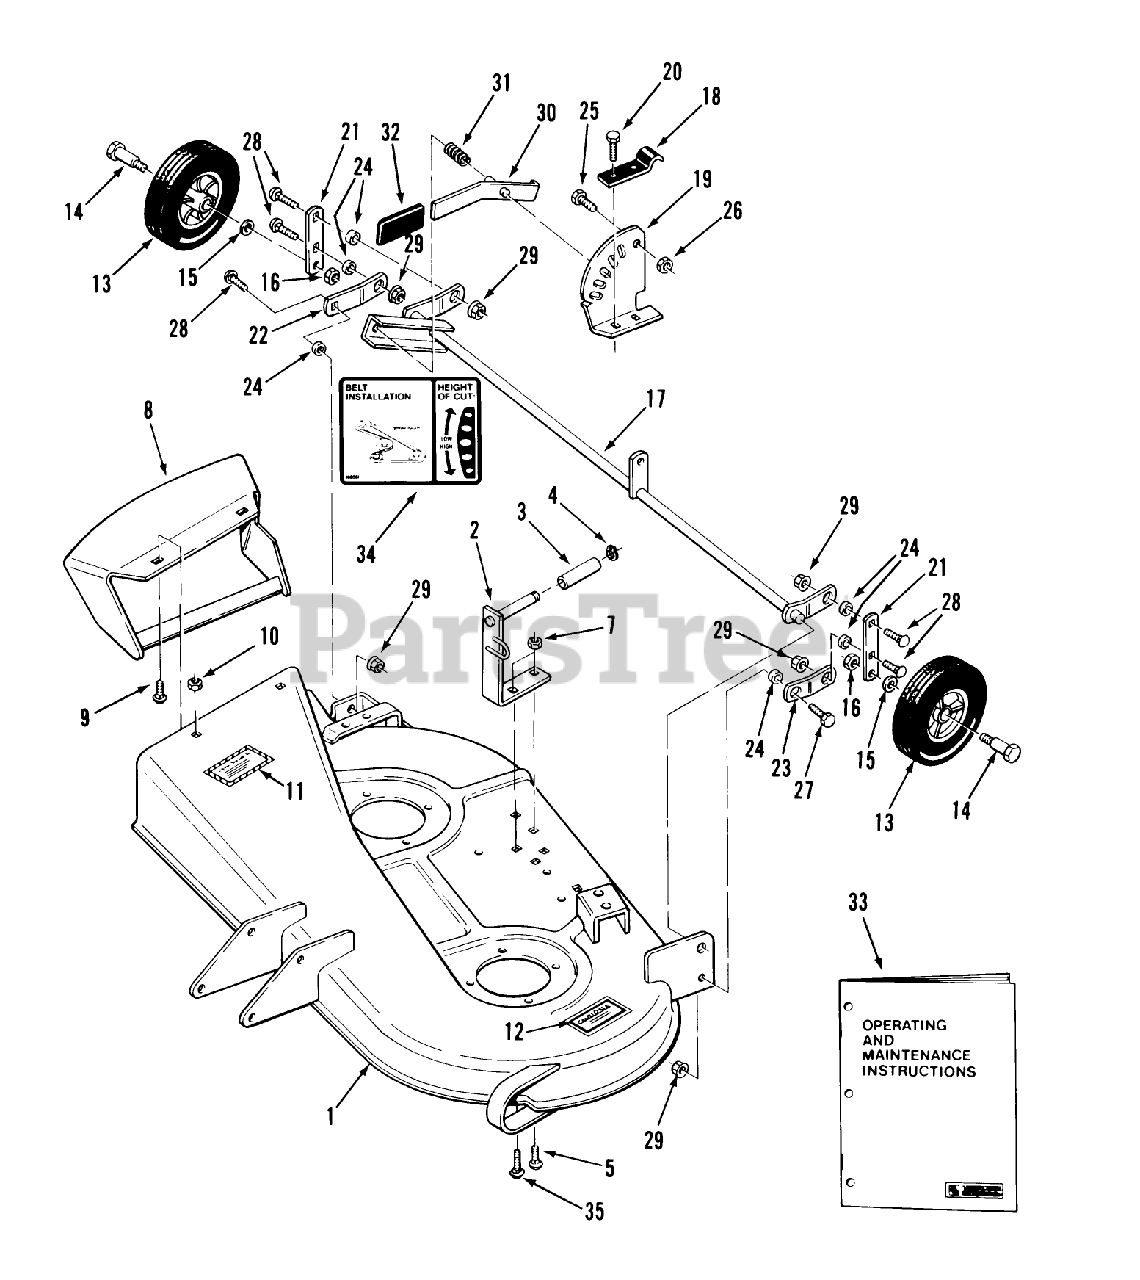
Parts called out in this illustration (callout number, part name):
20	Bolt
24	SPACER
31	SPRING-COMPRESSION
33	Operating Maintenance Instructions
